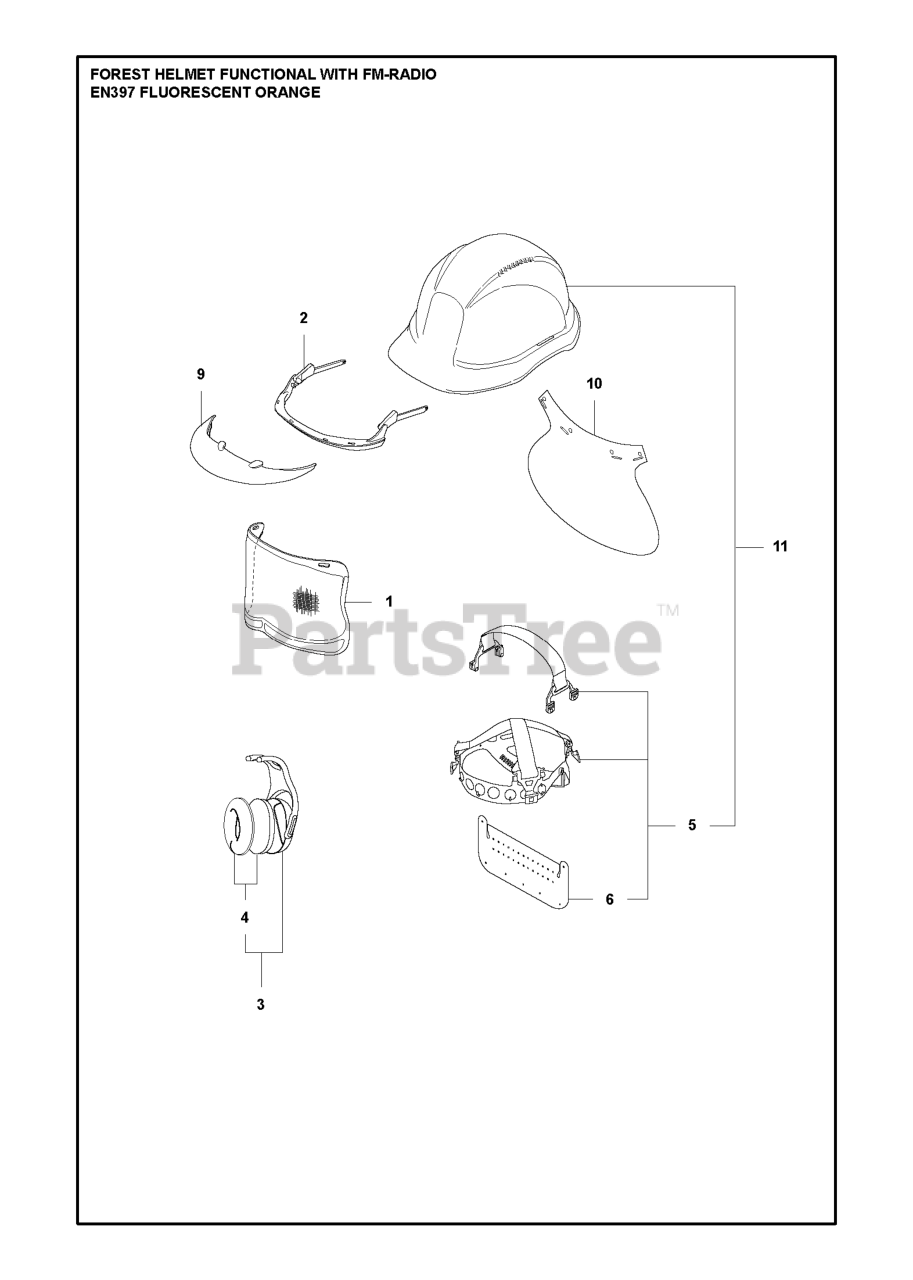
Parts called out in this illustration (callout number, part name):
1	ULTRA VISON VISOR XS
2	VISOR ARM/HOLDER
3	FM RADIO SET FOR HELMET
5	SPHARNESS F HELMET H200/BALANC
6	SWEATBAND FOR HELMET
9	VISOR SHIELD N/A FOR HELMET
10	Rain Protector for neck
